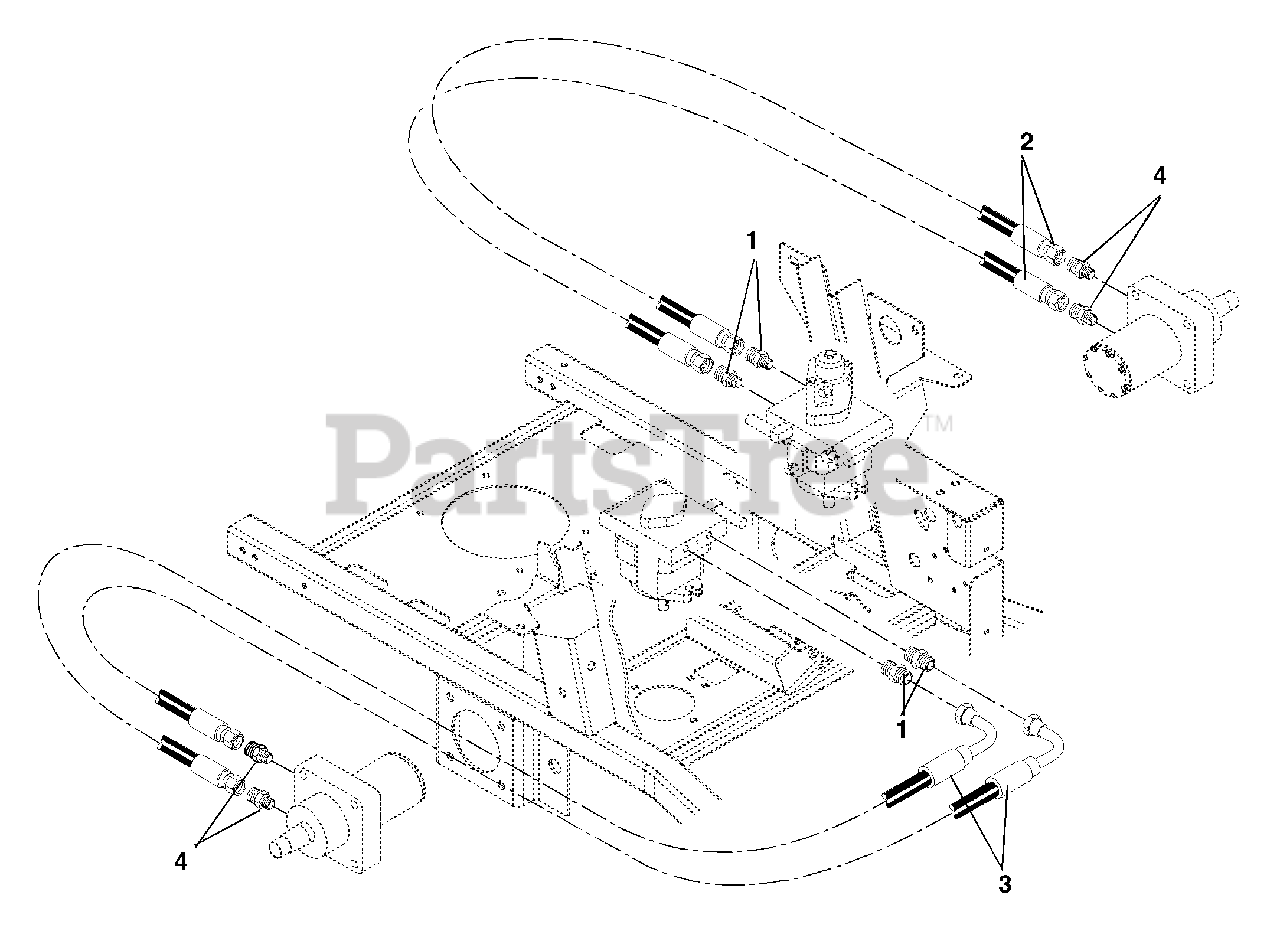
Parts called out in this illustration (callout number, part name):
1	Adapter-Hydraulic Steel .75 to .75
2	Hose-Hydraulic .50 18.75 Long
3	Hose-Hydraulic .50 x 29.50 Long
4	Adapter-Hydraulic Steel .875 to .75
